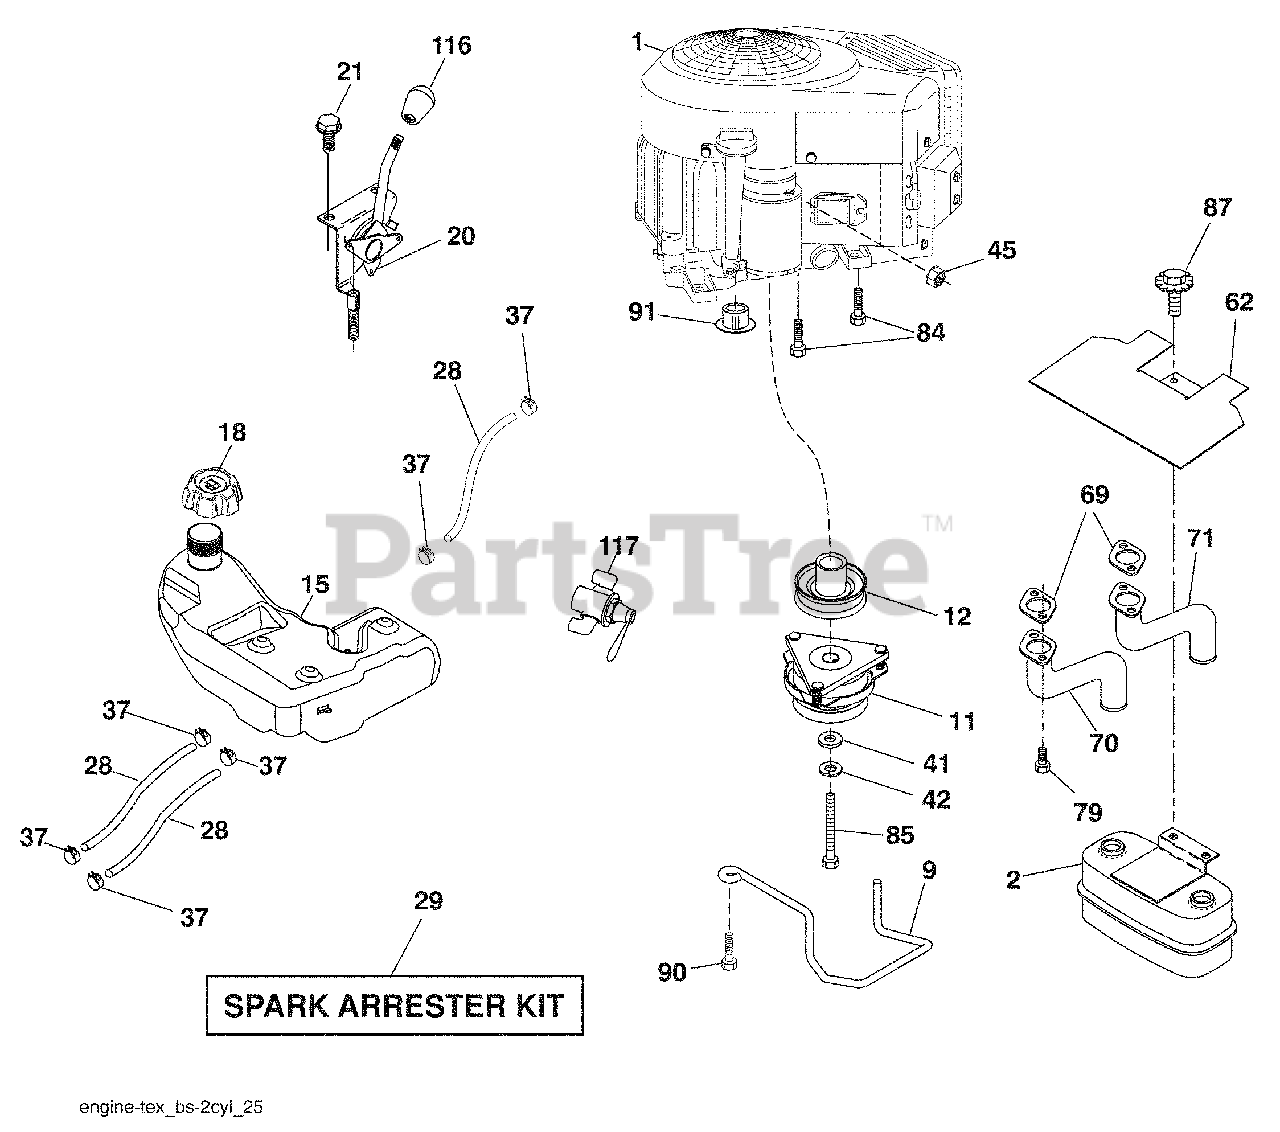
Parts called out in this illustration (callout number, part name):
9	Keeper Belt Engine
11	Clutch Electric
12	Pulley Engine
18	Cap Asm
20	Control Throttle
21	Screw #10 x 0.750 BOS Thread
28	Fuel Line
29	Spark Arrester Kit
37	Clamp Hose
41	Washer 1-1/2 OD x 15/32 ID x .250
42	Washer Lock 7/16
45	Nut Keps Hex 1/4-20 unc
62	Shield Heat Muffler
70	Tube Exhaust LH
71	Tube Exhaust RH
79	Screw Socket Head
84	Screw 3/8-16 x 1-1/4
85	Bolt Hex 7/16-20 x 3.75 Gr. 5
87	Bolt 5/16-18 unc x 1 w/Sems
90	Screw 3/8-16 x 1
91	Bushing 1.375 OD
116	Knob Soft Touch
117	Valve Fuel Reserve
